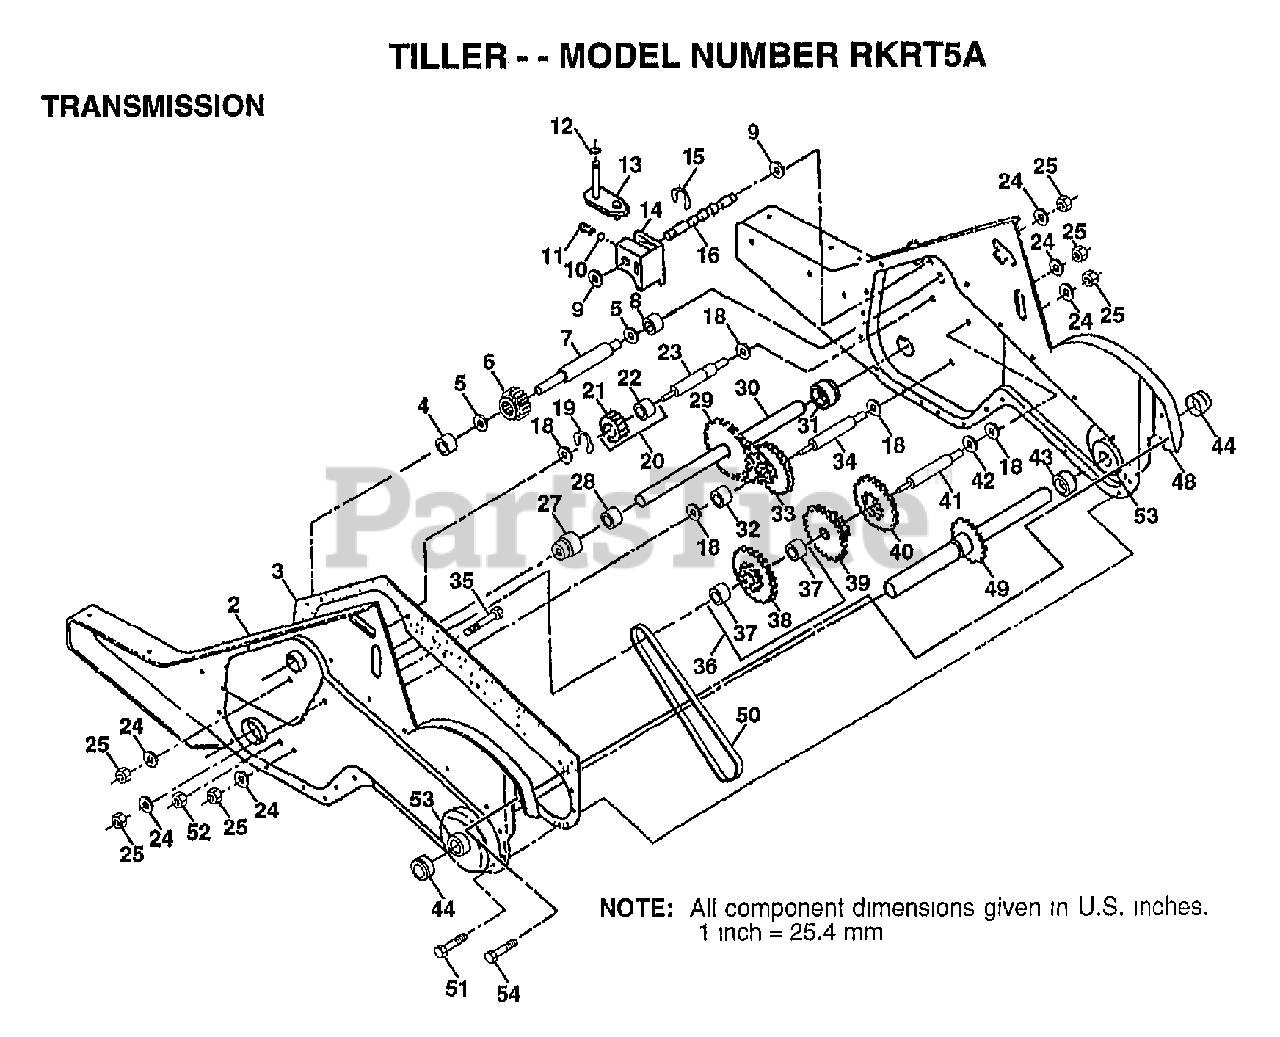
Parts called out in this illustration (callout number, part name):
2	GEARCASE LH W/BEARING
3	GASKET.GEARCASE
4	NEEDLE BRNG LT
5	"T, BEARING"
6	GEAR PINION INPUT
7	"SHAFT.INPUT.""D"""
8	"TI, BEARING"
9	WASHER SEAL
11	SPRING-SHIFT CRT
12	O-RING TI
13	BRACKET ASM SHIFT
14	SHIFT FORK TI
15	KLIP RING
16	SHAFT.SHIFTER
18	WASHER
19	KLIP RING
20	GEAR ASSY CRT
21	GEAR-REV IDLR CRT
22	NEEDLE BEARING TI
23	SHAFT CRT
24	LOCKWASHER
25	NUT.ASF.HEX.7/16
27	BEARING.SHAFT.LH.
28	BUSHING TI
29	CHAIN CRT
30	GROUND SHAFT ASSY
31	BEARING.SHAFT.RH.
32	SPACER TI
33	SPRCKT 8 GEAR CRT
34	SHFT 2ND RED. CRT
35	SCRW WHIZ LOK CRT
36	SPROCKET.ASM.W/BR
37	BEARING
39	GEAR TI
40	GEAR TI
41	REDUCTION SHFT TI
42	BRNG RACE
43	SPACER TI
44	SEAL ASM-OIL
48	GEARCASE RH W/BEARING
49	TINE SHAFT
50	CHAIN.50 LINK TI
51	SCREW
52	NUT.HEX.5/16-18
53	KIT.BEARING
54	SCREW 1/4-20X3/4
